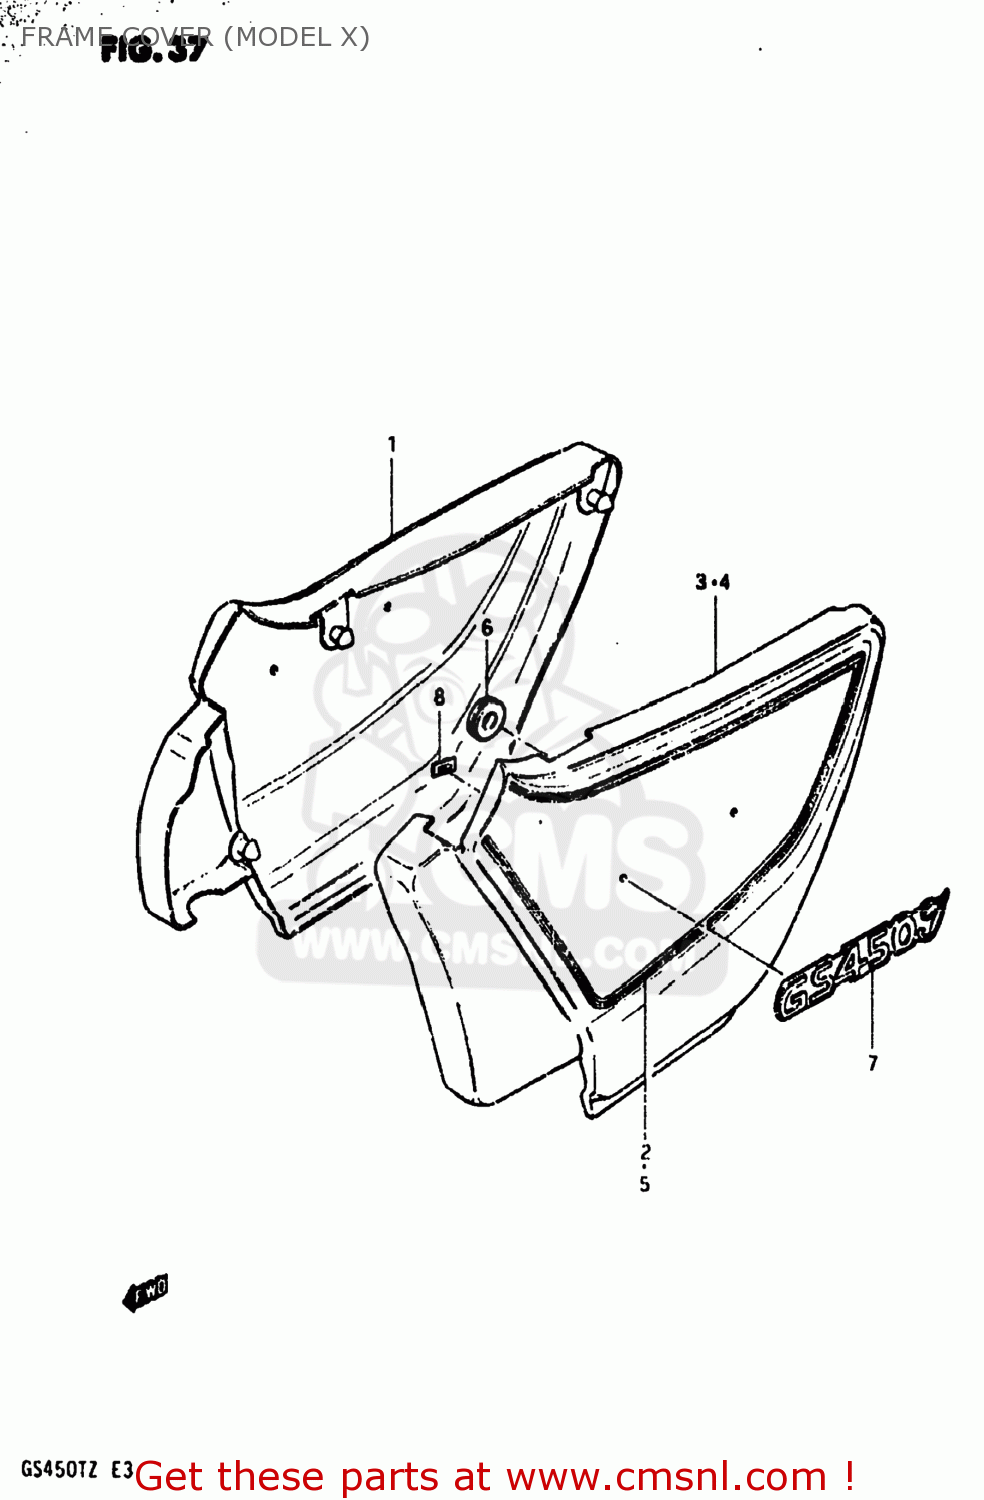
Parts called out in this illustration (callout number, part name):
1	COVER,FRAME,RIGHT
2	TAPE SET,FRAME COVER
3	COVER,FRAME,LEFT
4	COVER,FRAME,LEFT
5	TAPE SET,FRAME COVER
6	CUSHION
7	EMBLEM,FRAME COVER
8	NUT
